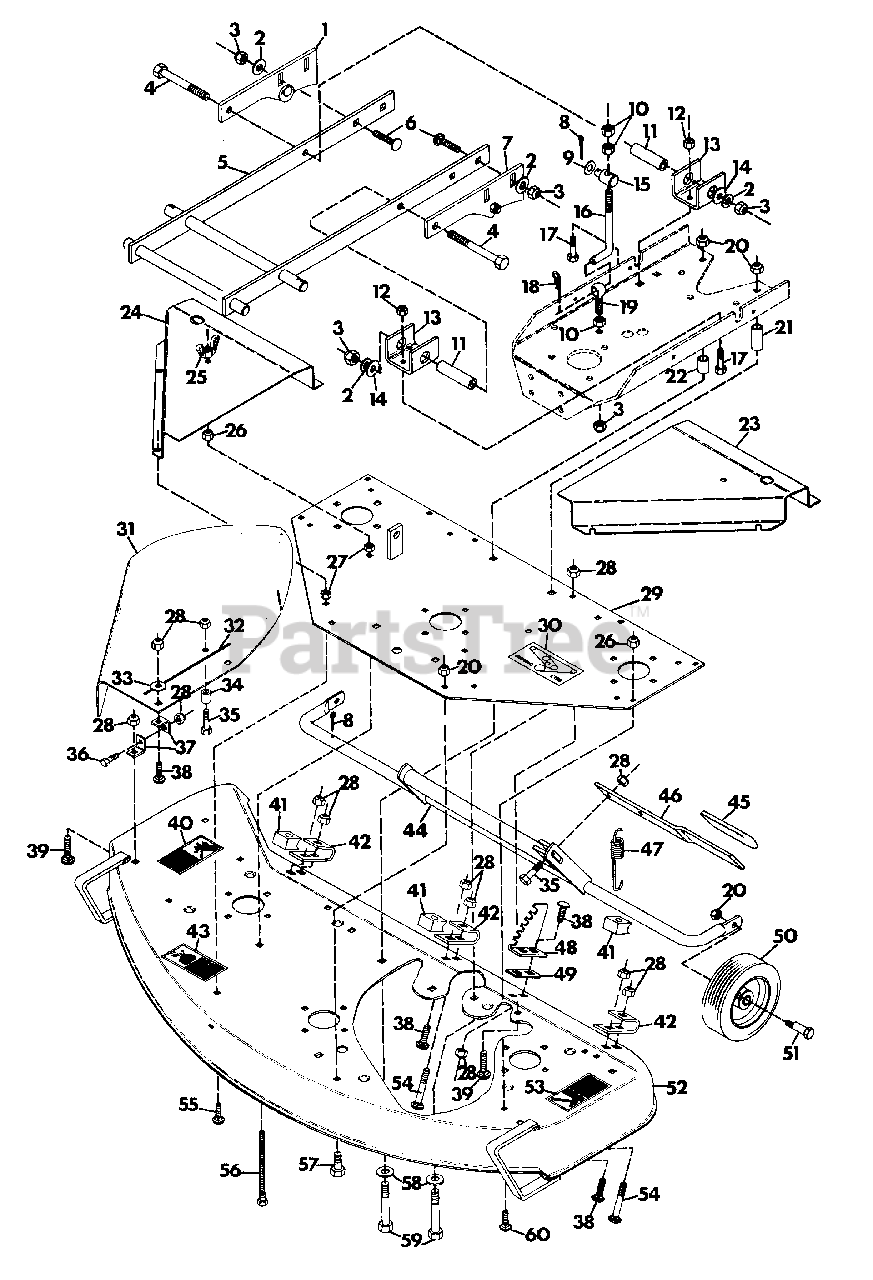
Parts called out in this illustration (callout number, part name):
1	WELDMENT, DECK LEVELING R.H.
2	WASHER, FLAT .531X1.250X.100
3	NUT, LOCK 1/2-13
4	BOLT, HEX 1/2-13X3.25
5	WELDMENT, PIVOT ARM
6	BOLT, CARRIAGE 1/2-13X1.25
7	WELDMENT, DECK LEVELING L.H.
8	PIN, COTTER .125X1.250
9	WASHER, FLAT .531X1.000X.063
10	NUT, JAM 1/2-13 HEX
11	BUSHING, PIVOT .510X.750X2.020
12	NUT, LOCK 5/16-18
13	SUPPORT, MOWER PIVOT
14	WASHER, FLAT .813X1.37X.100
15	PIVOT, MOWER LIFT
16	ROD, LIFT
17	BOLT, HEX 5/16-18X.875
18	PIN, COTTER HAIR
19	BOLT, EYE
20	NUT, LOCK 1/2-13
21	SPACER, .510X.840X2.43
22	SPACER
23	COVER, PULLEY L.H.
24	COVER, PULLEY R.H.
25	NUT, WING 5/16-18
26	NUT, LOCK 5/16-18
27	NUT, JAM 5/16-18 HEX
28	NUT, LOCK 3/8-16
29	WELDMENT, SUPPORT PLATE
30	DECAL, BELT INSTALLATION
31	SHIELD, SAFETY EXTENSION
32	STRIPE
33	WASHER, FLAT .406X.812X.065
34	STOP, CHUTE
35	BOLT, HEX 3/8-16X1.50
36	BOLT, HEX 3/8-16X.875
37	TAB, SPRING
38	BOLT, 3/8-16X1 RD HD SQ NK
39	BOLT, CARRIAGE 3/8-16X.75
40	DECAL, DANGER HAND
41	STOP, NYLON
42	BRACKET, AXLE SUPPORT
43	DECAL, WARNING EYE
44	WELDMENT, AXLE PIVOT
45	GRIP, HANDLE
46	LEVER, HEIGHT OF CUT
47	SPRING, 40 AND 50 INCH MOWER
48	BRACKET, HEIGHT ADJUST
49	SHIM, MOWER HT. ADJ. BRKT.
50	WHEEL, GAUGE
51	BOLT, ECCENTRIC
52	WELDMENT, 50 INCH DECK
53	DECAL, DANGER FOOT
54	BOLT, 3/8-16X2 RD HD SQ NK
55	BOLT, CARRIAGE 5/16-18X1.00
56	BOLT, HEX 5/16-18X3.50
57	BOLT, HEX 1/2-13X1.25
58	WASHER, FLAT .531X1.062X.095
59	BOLT, HEX 1/2-13X3.75
60	BOLT, CARRIAGE 5/16-18X.75
NS	BAFFLE
